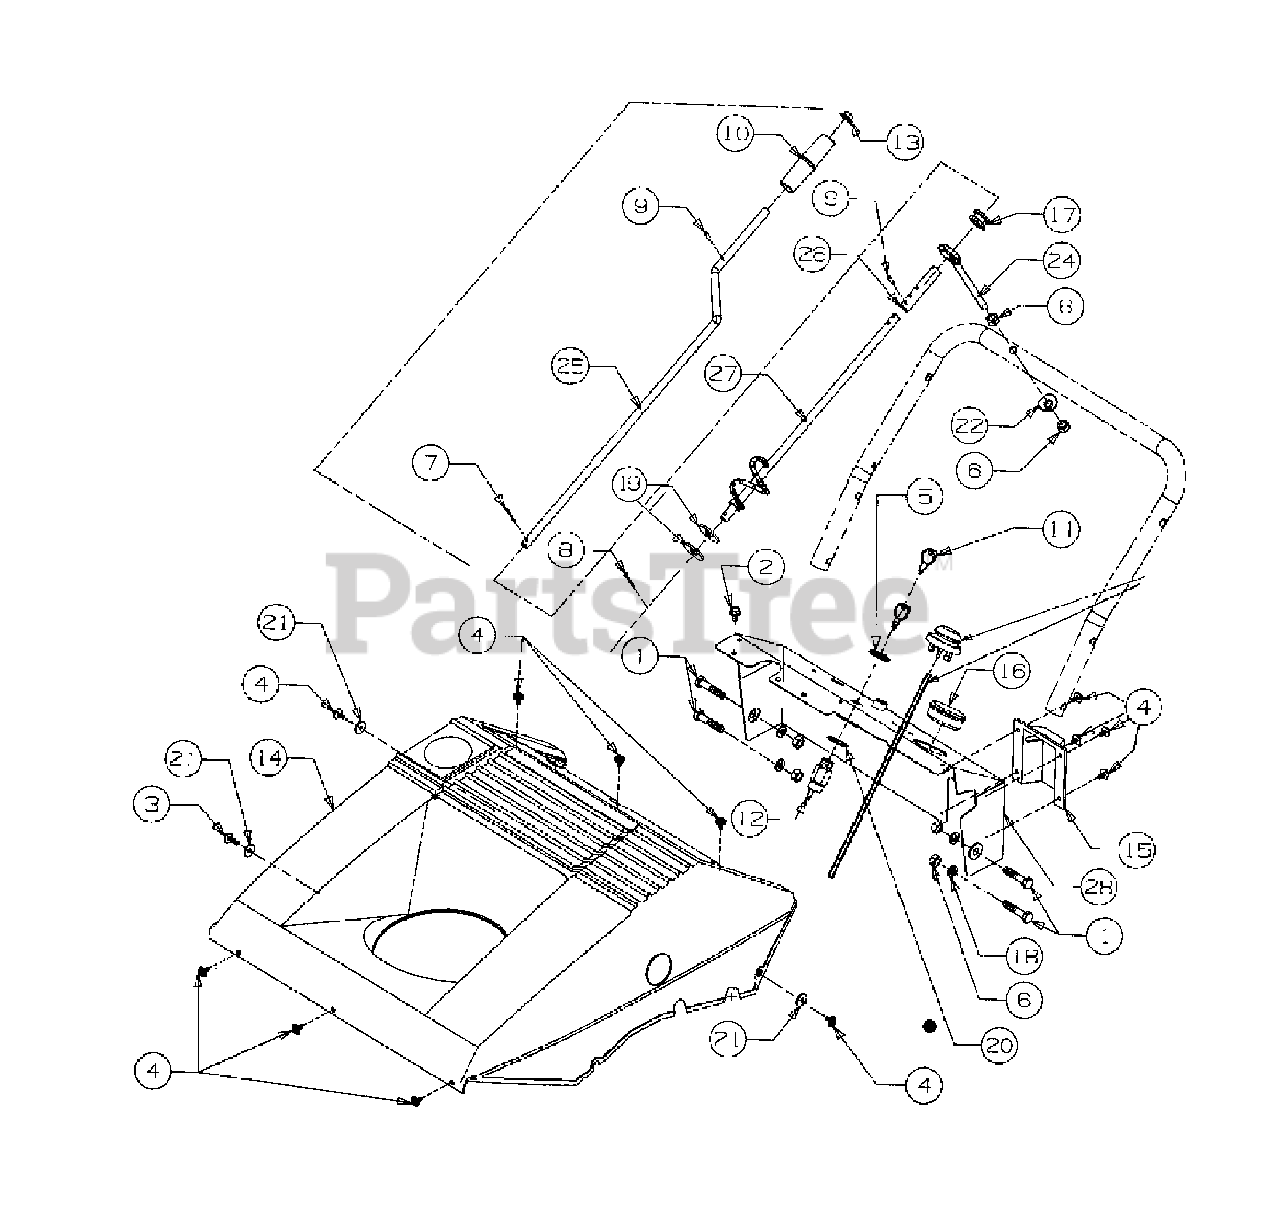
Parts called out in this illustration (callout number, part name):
1	Hex Screw
2	Hex Washer Screw
3	Hex Screw
4	Hex Screw
5	Jam Nut
6	Hex Nut
7	Hairpin Clip
8	Cotter Pin
11	Key-Ignition
12	Switch
13	Cap-Push
14	Shroud-Black
15	Cover-Choke
16	Plug-Insert
17	Grommet-Rubber
18	Lock Washer
19	Flat Washer
20	Internal Lock Washer
21	Flat Washer
22	Saddle Washer
24	Eyebolt, Chute Crank
26	Spacer
